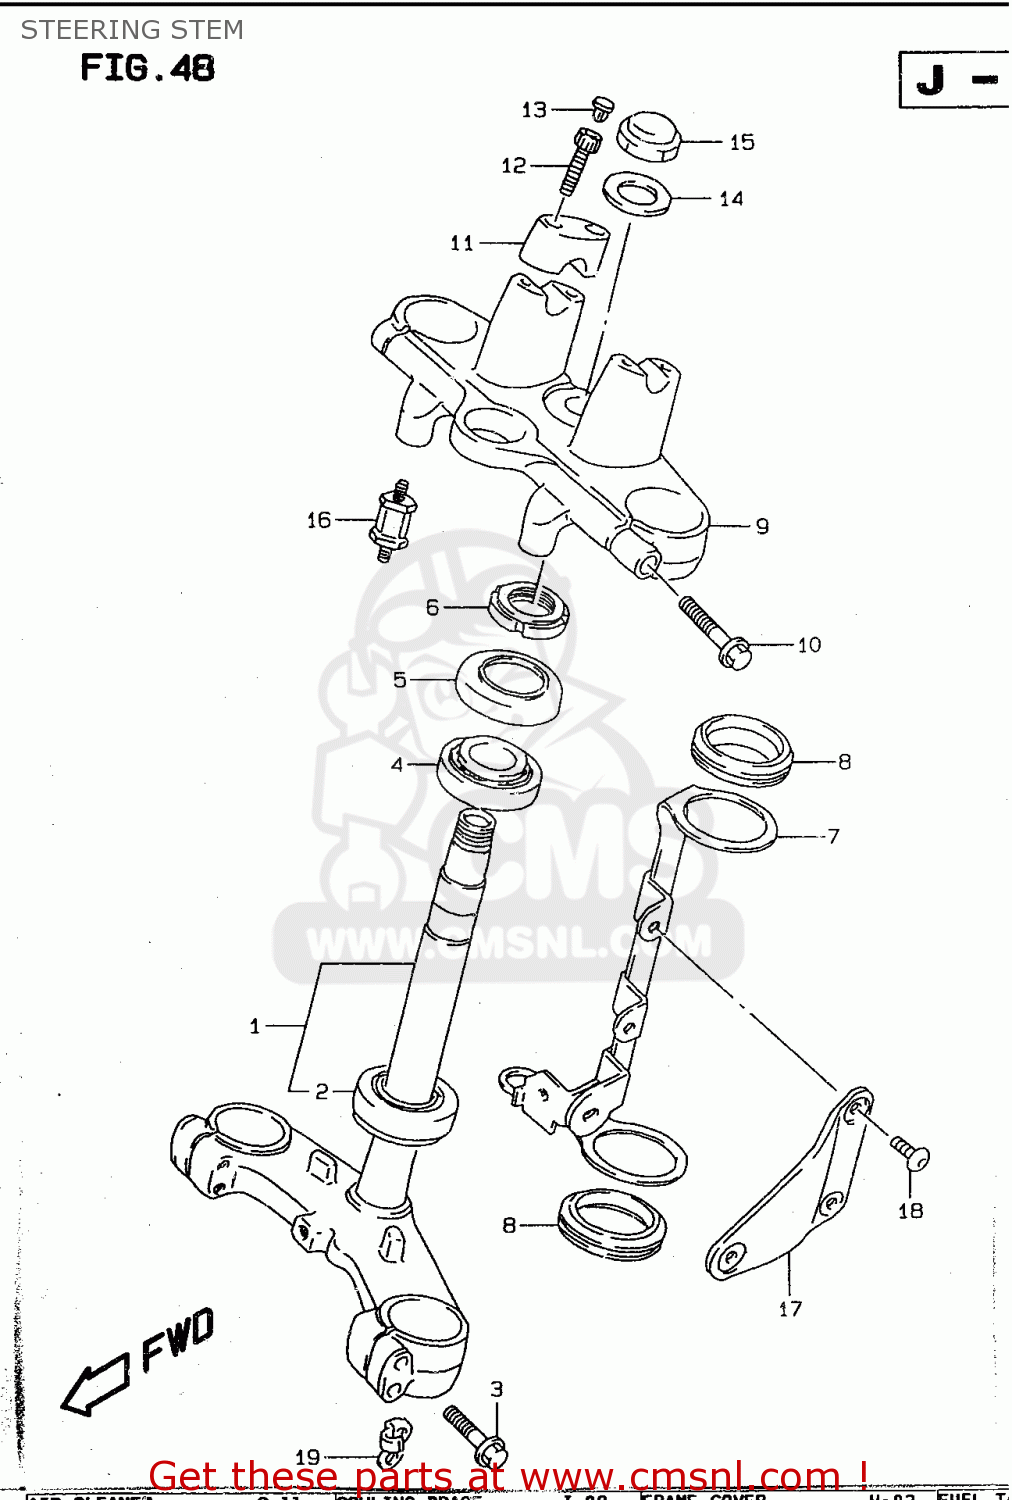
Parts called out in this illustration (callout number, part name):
1	STEM,STEERING
2	BEARING(30X55X17)
3	BOLT
4	BEARING(25X47X15)
5	SEAL,STEERING UPR DUST
6	NUT,STEERING STEM(25X44X10)
7	BRACKET,HEADLAMP HOUSING,R
8	DAMPER,HEADLAMP HSG BRACKET
9	HEAD,STEERING STEM
10	BOLT
11	HOLDER,HANDLE UPR
12	BOLT
13	CAP(OD:11)
14	WASHER(22.5X35.9X1.6)
15	NUT,CAP
16	BOLT,SPEEDOMETER CUSHION
17	STAY,HEADLAMP HOUSING,R
18	SCREW(6X12)
19	GUIDE,SPEEDOMETER CABLE
